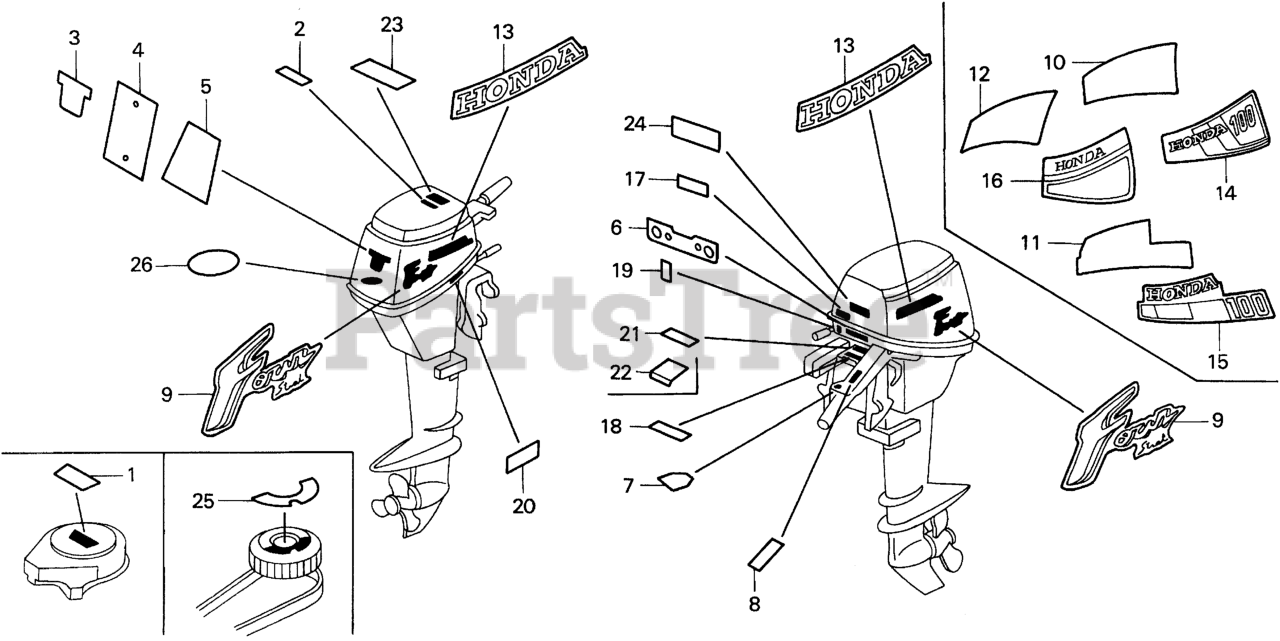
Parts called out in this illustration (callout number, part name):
2	MARK, INSTRUCTION
4	EMBLEM, RR. (NOT AVAILABLE)
6	LABEL, INDICATION (NOT AVAILABLE)
7	MARK, HANDLE FOREIGN (NOT AVAILABLE)
10	EMBLEM, R. SIDE COVER (NOT AVAILABLE)
14	EMBLEM, L. SIDE COVER (NOT AVAILABLE)
19	MARK, CHANGE (NOT AVAILABLE)
20	LABEL, OIL FILLER POSITION (NOT AVAILABLE)
22	PLATE, SETTING CAUTION (NOT AVAILABLE)
23	MARK, STARTER CAUTION
24	MARK, FR. (NOT AVAILABLE)
